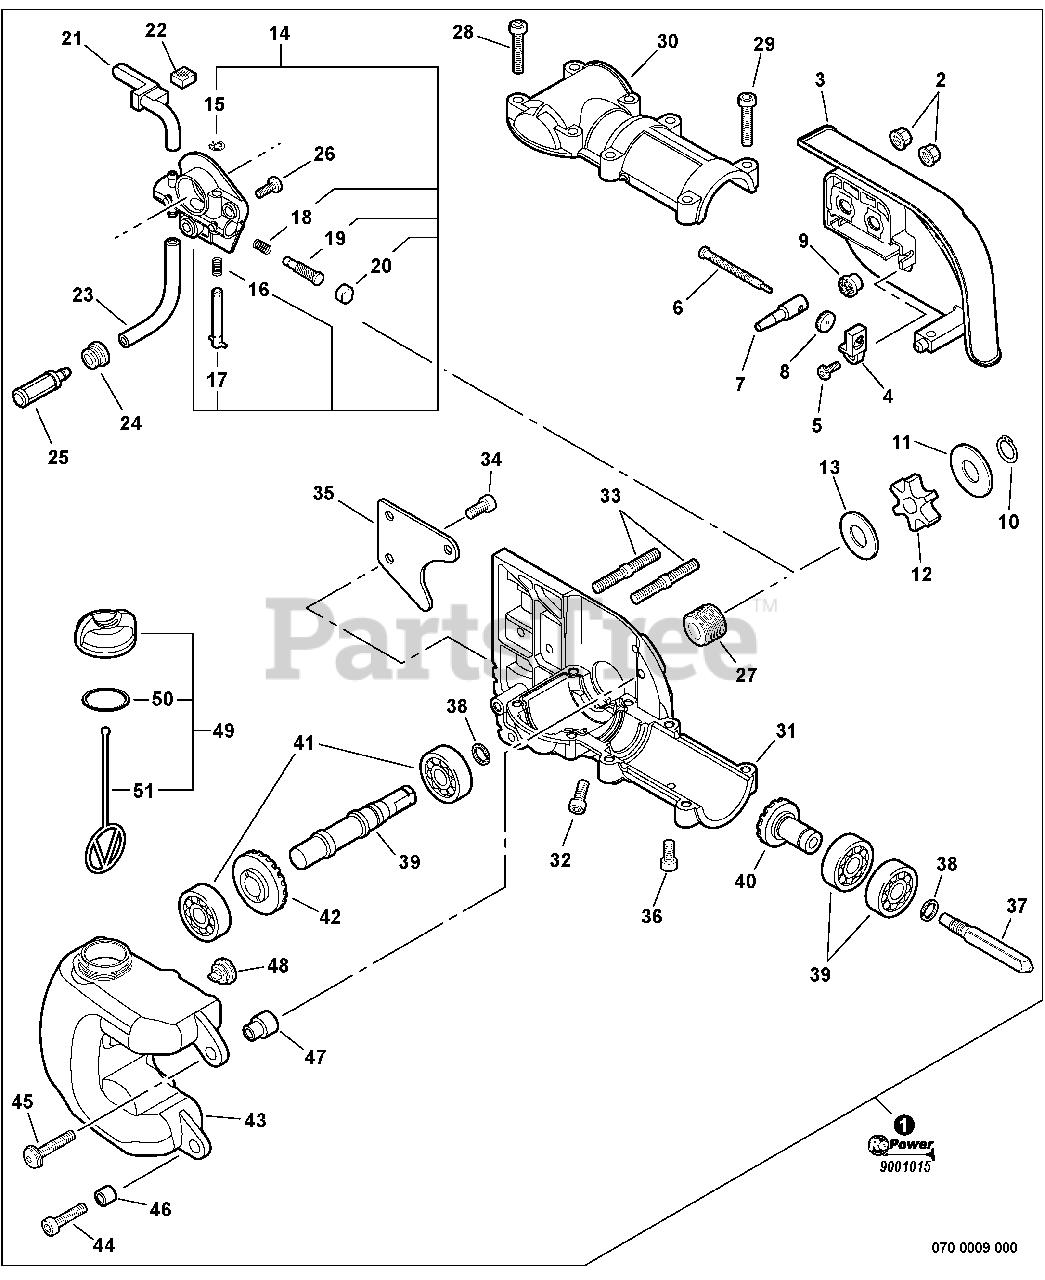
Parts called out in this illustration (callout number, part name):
1	CUTTING HEAD ASSY
2	NUT - 6 -- FLANGE
3	GUARD, SPROCKET
4	BRACKET, TENSIONER
5	SCREW - 4X8
6	SCREW, TENSIONER
7	TENSIONER, CHAIN
8	GEAR - BEVEL
9	GEAR - BEVEL
10	RING, RETAINING
11	WASHER - 10
12	SPROCKET, DRIVE
14	AUTO-OILER ASSY
15	RING, RETAINING
17	NEEDLE, ADJUST
19	PLUNGER
20	CAP, OIL PUMP
21	PIPE, OIL OUTLET
22	PAD, FOAM
23	PIPE - 3X6X75 -- BLACK
24	GROMMET
25	FILTER, OIL
26	SCREW - 5X10
27	GEAR - WORM
28	SCREW - 5X25
29	SCREW - 5X25
30	CASE, GEAR - UPPER
31	CASE, GEAR - LOWER
32	SCREW - 5X10
33	STUD, GUIDE BAR
34	SCREW - 5X10
36	SCREW - 5X10
37	CONNECTOR, SHAFT
38	RING, RETAINING - 12
39	BEARING, BALL - 6001
40	GEAR - BEVEL
41	GEAR - SHAFT
42	GEAR - BEVEL
43	TANK, OIL
44	SCREW - 5X20
45	SCREW - 5X25
49	CAP ASSY - ORANGE
50	O-RING - 18
51	CONNECTOR, CAP
